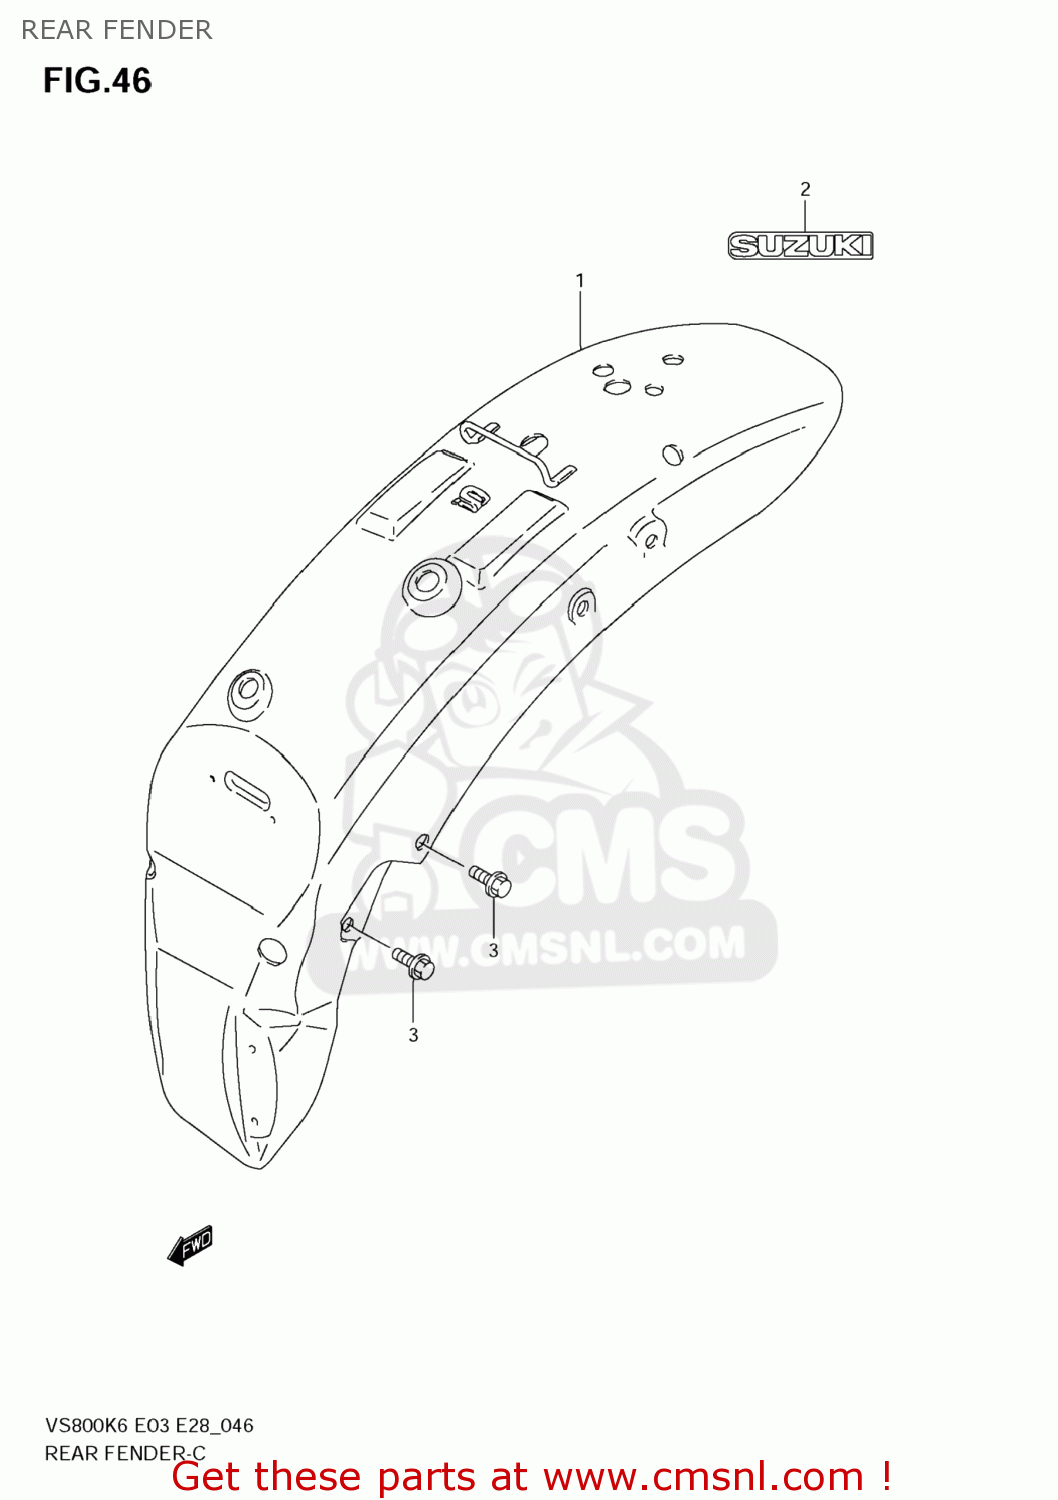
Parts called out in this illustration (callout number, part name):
1	FENDER ASSY,RR
2	EMBLEM,SUZUKI
3	BOLT
